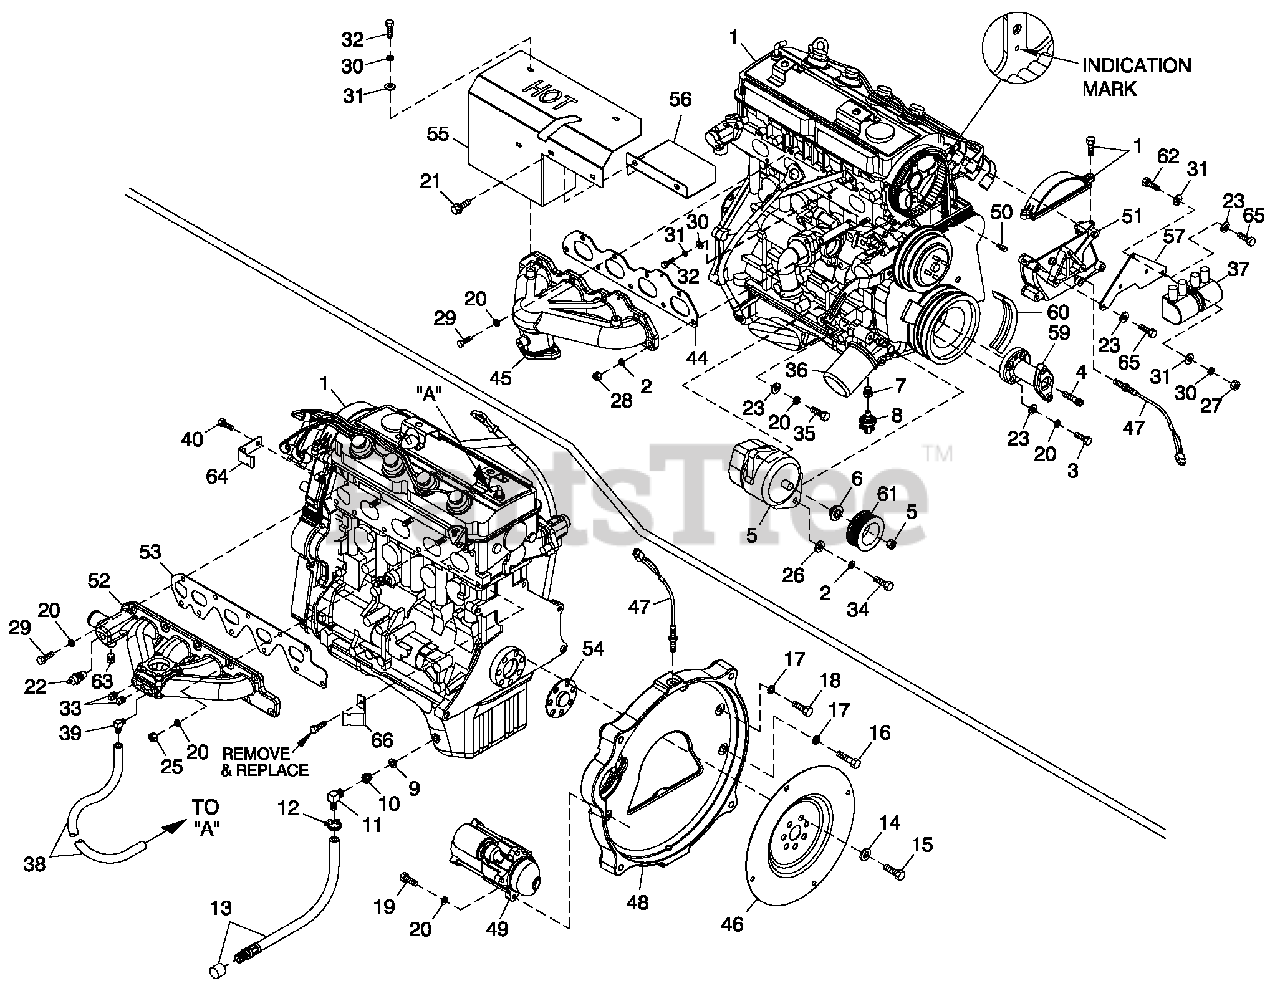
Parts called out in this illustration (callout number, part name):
1	ENGINE 2.4L MITSUBISHI 4G64
2	WASHER LOCK M10
3	SCREW HHCM8-1.25X 35 G8.8
4	SCREW SHC M14-1.5 X 35 G10.9
5	ALTERNATOR DC W/OUT PULLEY
6	SPACER DC ALTERNATOR PULLEY
7	ADAPTOR 1/8 NPTF TO 1/8 BSPT
8	SWITCH OIL PRESSURE 10 PSI 2 POL (R-PANEL)
9	WASHER NYLON .565
10	ADAPTER M14-1.50X 3/8 NPT
11	BARBED EL 90 3/8 NPT X 3/8
12	CLAMP HOSE .38-.87
13	HOSE DRAIN ASSY 28"
14	WASHER FLAT .531 ID X 1.062 OD
15	SCREW HHC M12-1.25 X 20 G10.9
16	SCREW HHC M10-1.25 X 45 G8.8
17	WASHER SHAKEPROOF EXT 7/16 STL
18	SCREW HHC M10-1.25 X 30 G8.8
19	SCREW SHC M8-1.25 X 30 G12.9
20	WASHER LOCK M8-5/16
21	SCREW THF M6-1 X 16 N WA Z/JS
22	SWITCH HI-TEMP 245D X 3/8 NPT (R-PANEL)
23	WASHER FLAT 5/16-M8 ZINC
25	NUT HEX M8-1.25 G8 CLEAR ZINC
26	WASHER FLAT 3/8-M10 ZINC
27	NUT HEX M6 X 1.0 G8 YEL CHR
28	NUT HEX M10-1.25 G8 YEL CHR
29	SCREW SHC M8-1.25 X 25 G12.9
30	WASHER LOCK M6-1/4
31	WASHER FLAT 1/4-M6 ZINC
32	SCREW HHC M6-1.0X 12 G8.8
33	PLUG STD PIPE 1/4 STEEL SQ HD
34	SCREW HHC M10-1.5X 60 G8.8
35	SCREW HHC M8-1.25 X 25 G10.9
36	OIL FILTER G2 ENGINE
37	COIL PACK
38	HOSE 3/8 ID SINGLE BRAID (15" LG)
39	BARBED EL 90 1/4 NPT X 3/8
40	SCREW HHC M6-1.0X 25 G8.8
44	GASKET EXHAUST MANIFOLD
45	EXHAUST MANIFOLD G2 (MACHINE)
46	FLEX PLATE 2 POLE 2.4L G2
47	ASSY MAGPICKUP(3/8-24 MALE)
48	ADAPTER ENGINE 2.4L MACHINE
49	STARTER, 12 VOLT
50	CAM SENSOR PIN ASSY
51	COVER CAM GEARG2 REWORKED
52	MANIFOLD INTAKE
53	GASKET INTAKE MANIFOLD
54	SPACER 2.4L G2 FLEX PLATE
55	SHIELD HEAT G2
56	SHIELD HEAT SML
57	BRACKET COIL PACK
59	ADAPTER 2.4L CRANKSHAFT MACH
60	POLY V-BELTG2 (3600 RPM)
61	PULLEY DC ALTERNATOR (3600 RPM)
62	SCREW HHC M6-1.0 X 35 G8.8 BLK
63	PLUG STD PIPE 3/8 STEEL SQ HD
64	BRACKET, SIGNAL CONDITIONER
65	SCREW HHC M8-1.25X 70 G8.8
66	BRACKET SIGNAL CONDITONER
